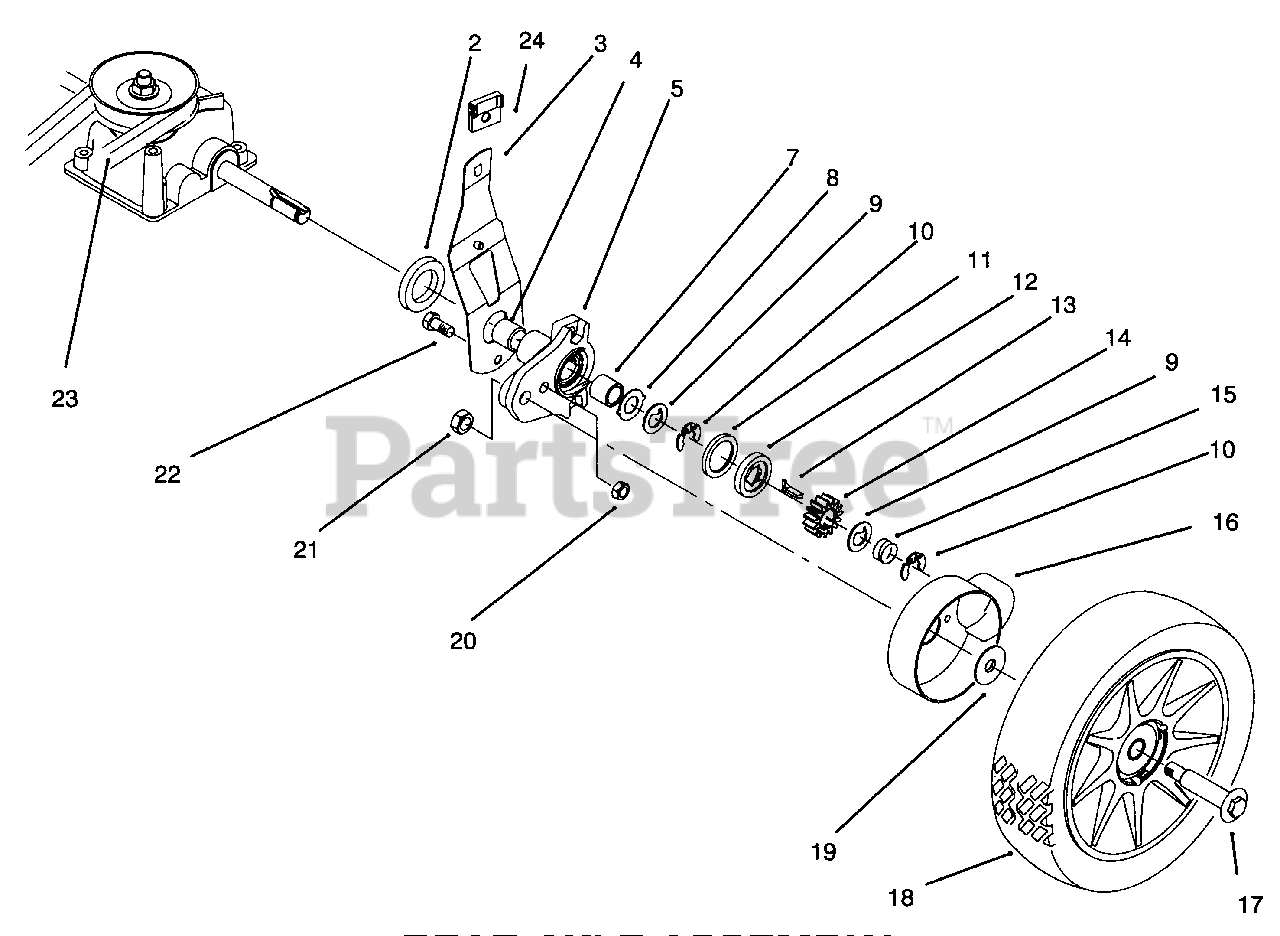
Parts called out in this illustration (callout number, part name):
2	Spacer-Axle Shaft
3	Spring Arm Ass'y
5	Pivot Arm Ass'y-Rear (Incl. Ref. #4, 6, & 7)
6	Fitting-Grease
8	Washer-Thrust Pivot Arm
9	Washer-Thrust, Keyed
10	Ring-Klip. Special
11	Ring-Friction
12	Washer-Clutch, Plastic
13	Key-Rocking, LH
14	Gear-Pinion
15	Spring-Compression
16	Cover Wheel
17	Bolt-Wheel
18	Wheel Ass'y-8"
19	Washer-Stepped
